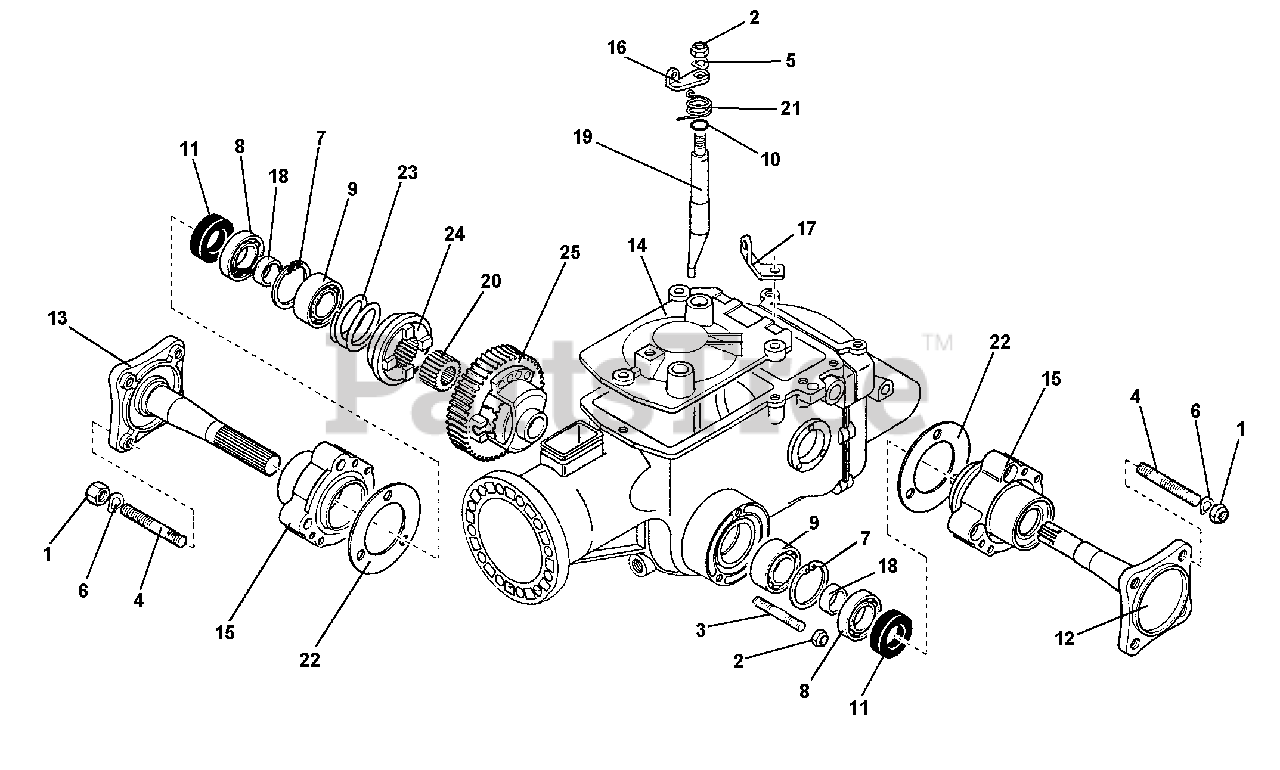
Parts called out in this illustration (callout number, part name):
2	NUT, SELF LOCKING, M8
3	STUD, M8X46X20X12
4	STUD, M10X40X22X14
5	WASHER, FLAT, M8.4
6	WASHER, LOCK, M10.5
7	CIRCLIP, INTERNAL
8	BEARING, M25X47X12
9	BEARING, M25X52X15
11	OIL SEAL, M30X40X7
12	HALF AXEL, L.H. SHORT
13	HALF AXEL, R.H. LONG
14	COVER DIFFERENTIAL
15	HUB FOR HALF AXLE
16	LEVER RELEASE
17	CONTRAST DIFFERENTIAL SHEATH
18	RING FOR HALF AXLE
20	SPACER GEAR FOR DIFFERENTIAL
22	JOINT GASKET
25	DIFFERENTIAL
